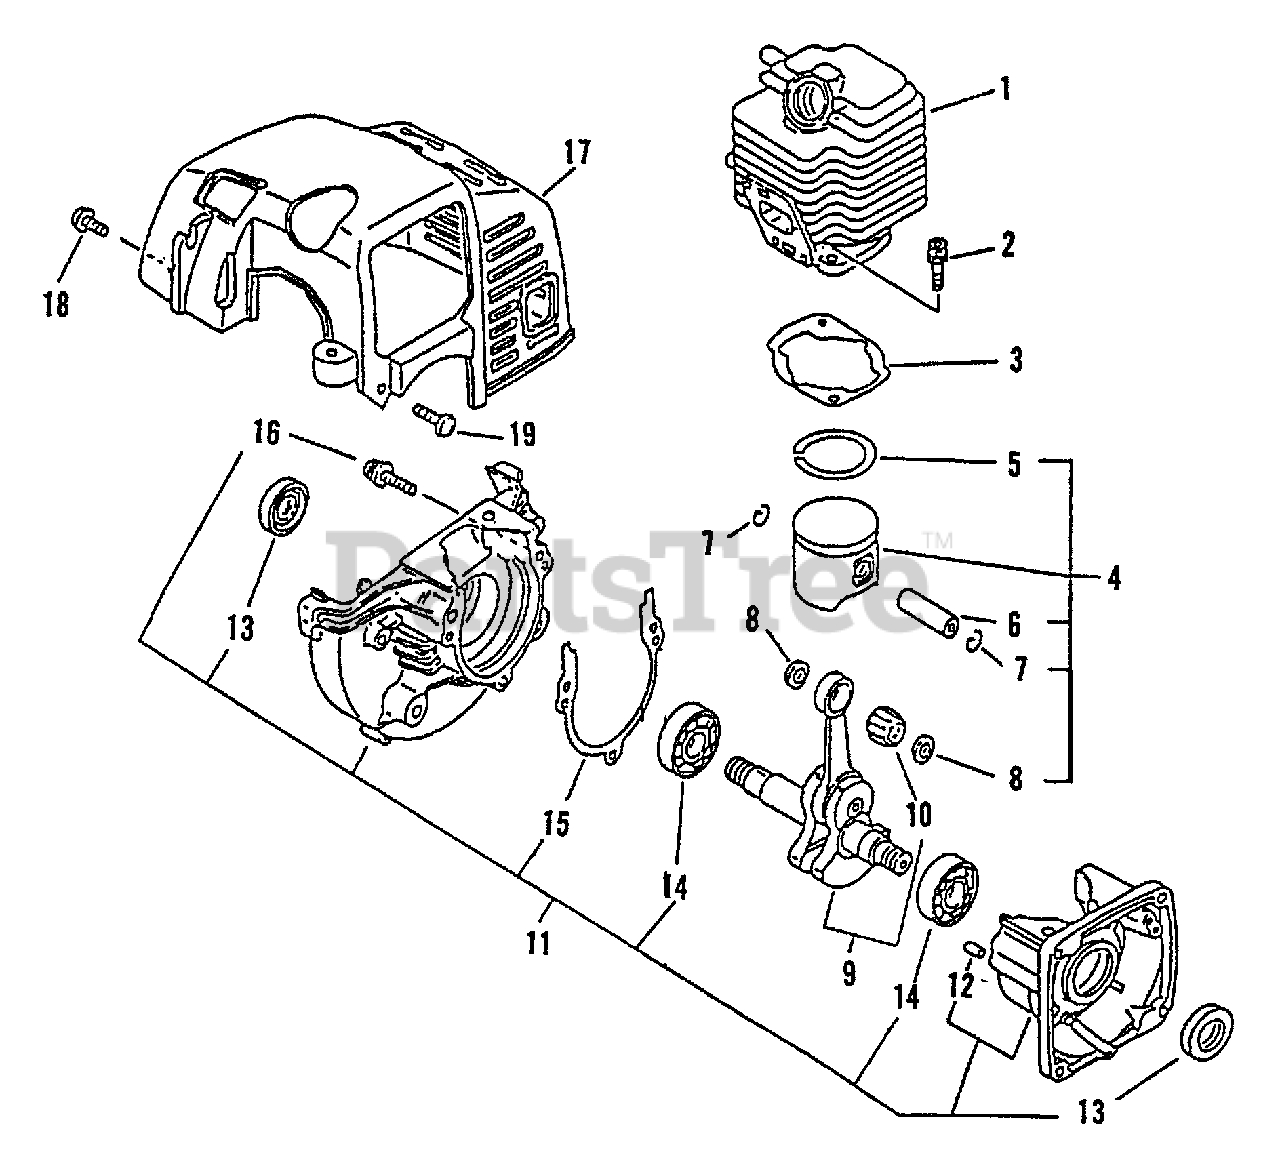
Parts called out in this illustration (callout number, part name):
1	CYLINDER
2	SCREW - 5X22
3	GASKET, CYLINDER
4	PISTON KIT
5	RING, PISTON
6	PIN, PISTON
7	RING, RETAINING
8	SPACER, PISTON
9	CRANKSHAFT ASSY
10	BEARING, NEEDLE
11	CRANKCASE KIT
12	PIN - LOCATING
13	SEAL, OIL
14	BEARING, BALL - 6201
15	GASKET, CRANKCASE
16	SCREW - 5X28
17	COVER, ENGINE
18	SCREW - 4X14
19	SCREW - 4X16
